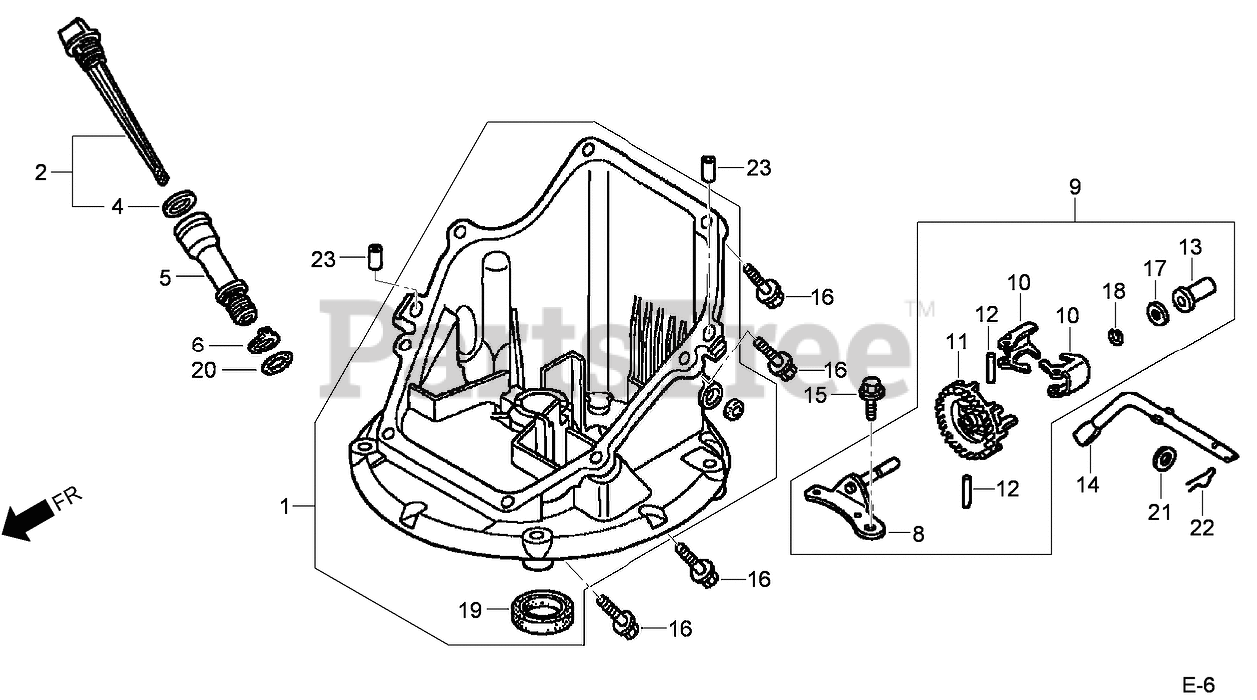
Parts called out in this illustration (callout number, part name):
1	OIL PAN ASM
2	OIL LEVEL GAUGE ASM
4	GASKET-CAP, OIL FILLER
5	EXTENSION-FILLER, OIL
6	WASHER-LOCK, EXTENSION
8	SHAFT-HOLDER, GOVERNOR
9	GOVERNOR ASM
10	WEIGHT-GOVERNOR
11	HOLDER-WEIGHT, GOVERNOR
12	PIN-WEIGHT, GOVERNOR
13	SLIDER-GOVERNOR
14	SHAFT-ARM, GOVERNOR
15	BOLT-FLANGE (6X14) (C T200)
16	BOLT-FLANGE (6X25) (C T 200)
17	WASHER-THRUST (6MM)
18	CLIP-HOLDER, GOVERNOR
19	SEAL-OIL (28X41.25X6)
20	O-RING (14.8X24) (N O K)
21	WASHER-PLAIN (6MM)
22	PIN-LOCK (8MM)
23	PIN-DOWEL (8X20)
